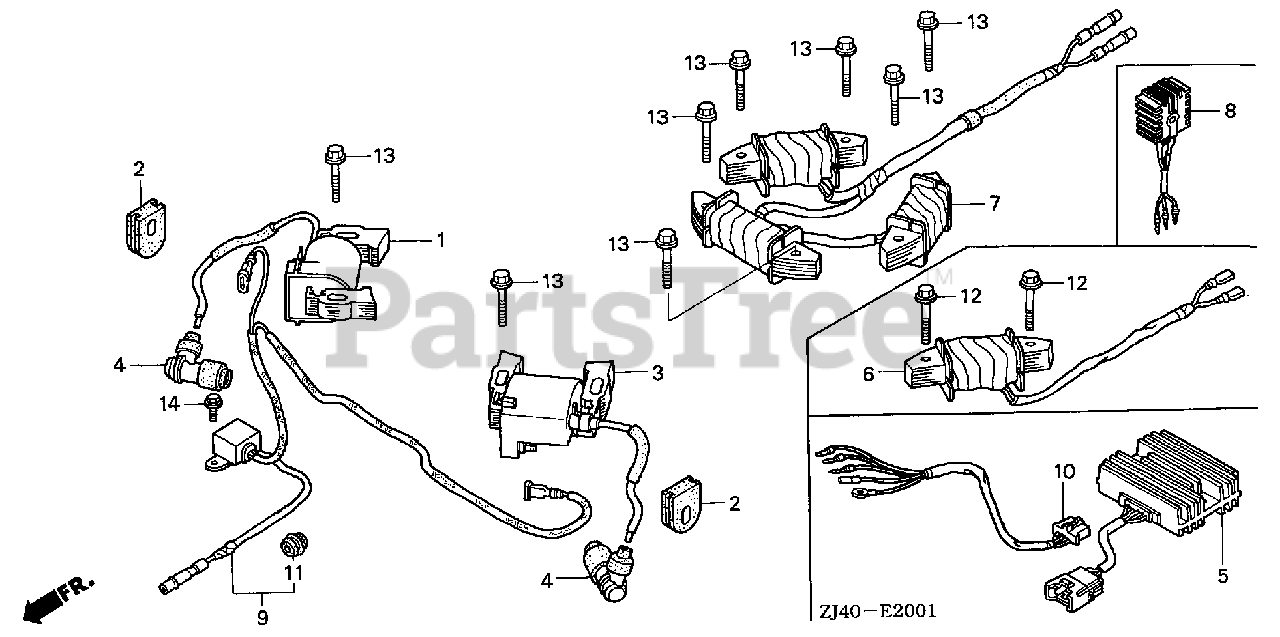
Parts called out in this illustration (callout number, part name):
1	COIL ASSY., IGNITION
2	GROMMET, IGNITION WIRE
3	COIL ASSY., IGNITION
4	CAP ASSY., NOISE SUPPRESSOR
5	RECTIFIER ASSY., REGULATOR (20A)
7	COIL ASSY., CHARGE (12V/20A)
9	DIODE ASSY., ENGINE STOP
10	SUB-WIRE HARNESS ASSY.
11	GROMMET, TOOL
13	BOLT, FLANGE (6X32) (CT200)
14	BOLT, FLANGE (6X8)
